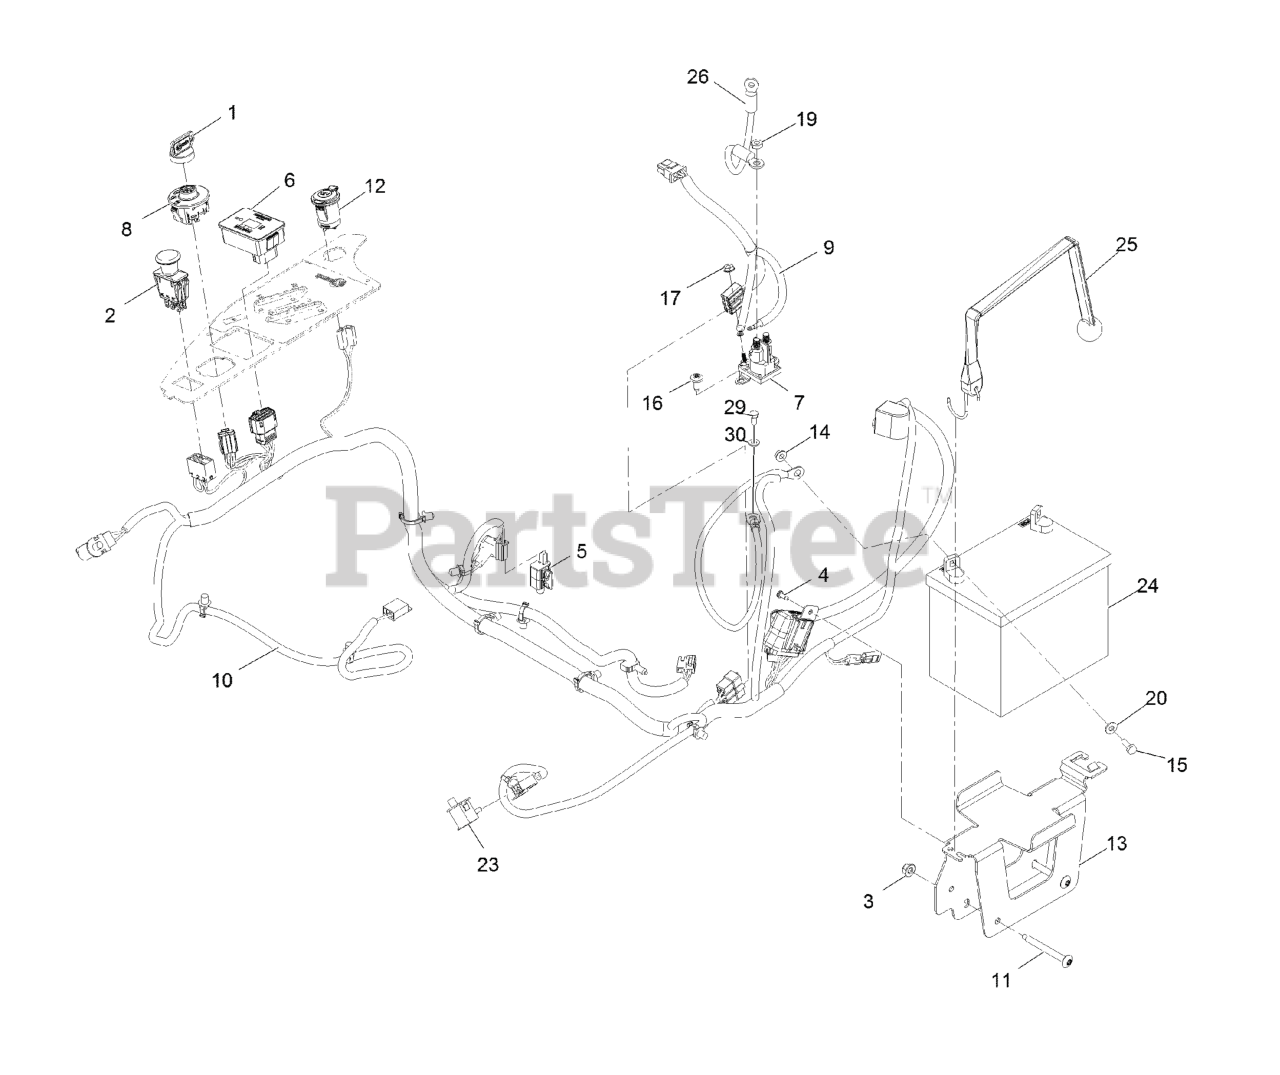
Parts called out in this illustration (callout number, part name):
1	KEYS-IGNITION (SPARE PAIR
1	KEY-IGNITION
2	SWITCH-PTO
3	NUT-HF, NI
4	SCREW-FORMING, THREAD
6	MODULE ASM
7	SOLENOID
8	SWITCH-IGNITION
9	ADAPTER-HARNESS, WIRE
10	HARNESS-WIRE
11	SCREW-TORX
12	PORT-POWER, 12V
13	TRAY-BATTERY
15	SCREW-HH
16	SCREW-TORX
17	NUT-KEPS
19	NUT-JAM
20	WASHER-FLAT
23	SWITCH-BAIL
24	Battery
25	STRAP-BUNGEE
26	CABLE-BATTERY, POSITIVE
29	SCREW-HH
30	WASHER-PLAIN
